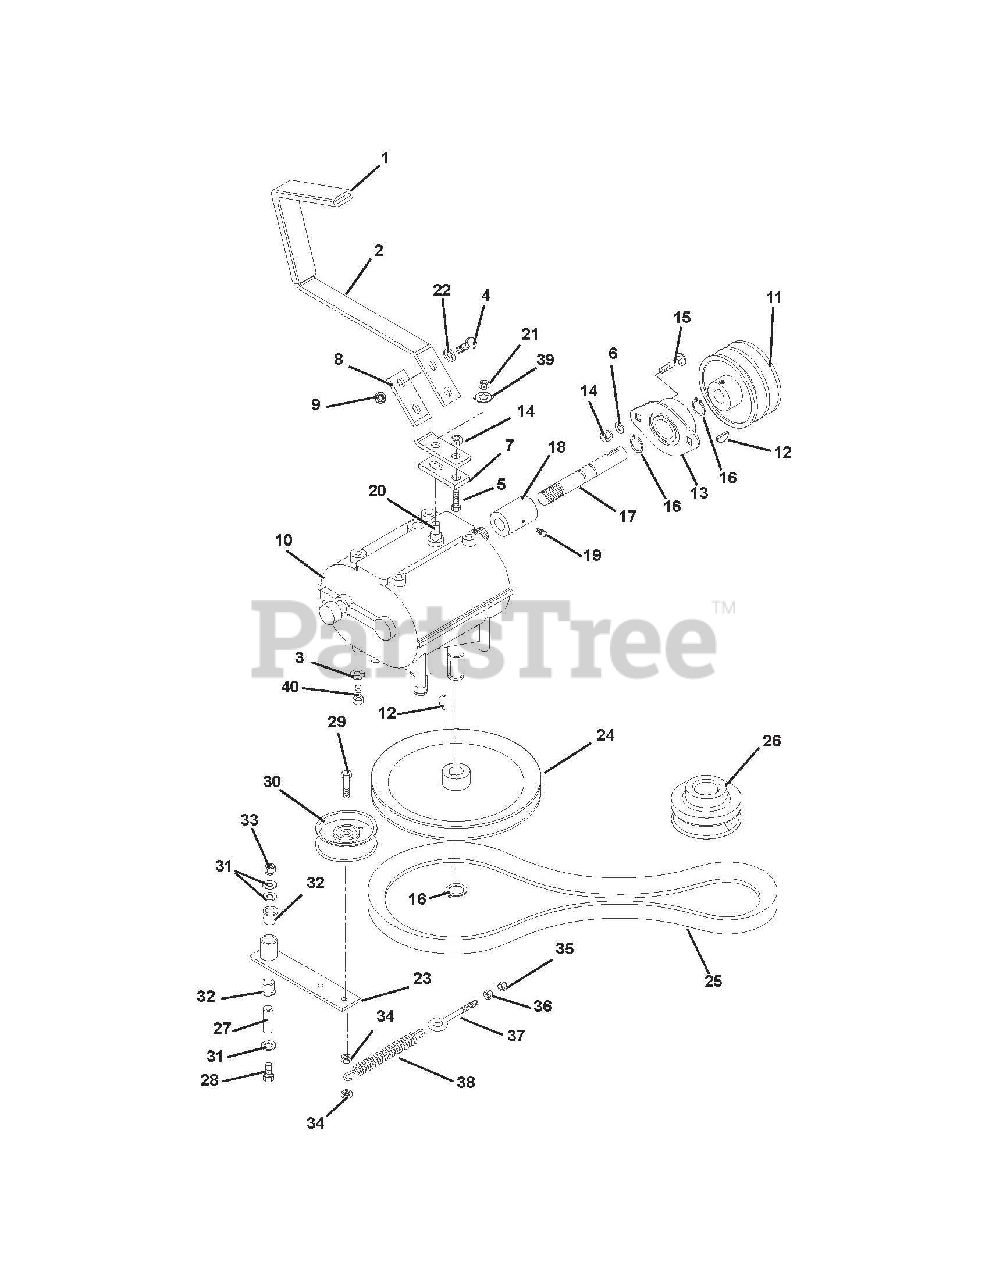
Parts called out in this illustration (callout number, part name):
2	Lever, Shifter
3	Washer-Locking .31 x .078 Regular
4	Bolt-Hex .31-18 x 1.00 Grade 5
5	Bolt-Hex .25-20 x 1.00 Grade 5
6	Washer-Flat-Steel .25 x .562 x .049
7	Plate, Shift
8	Arm, Shift
9	Nut-Locking-Top-Flange .31-18
10	Transmission
11	Sheave, Drive
12	Key-Woodruff .19 x .75
13	Bearing-Flange .625 x 1.875 x .797
14	Nut-Locking-Nylon .25-20
15	Bolt-Round Head Square Neck .25-20 x .75 Grade 5
16	Ring-Retaining-External .579 x .930
17	Shaft, Half
19	Fitting, Lube, .25-28
20	Switch-Neutral Start
21	Nut-Locking-Center .38-24
22	Washer-Flat-Steel .344 x .688 x .065
23	Weldment, Ground Drive Idler
24	Pulley-V 7.50 x .63 Sheave Transmission
25	V-Belt 4L-Section 34.385 x .531
27	Bushing, Steel .56 x .745 x 2.04
28	Bolt-Hex .50-13 x 3.25 Grade 5
29	Bolt-Hex .38-16 x 2.00 Grade 5
30	Idler-Pulley Flat 3.25 x .625
31	Washer-Flat-Steel .531 x 1.06 x .095
32	Bushing-Flange Nylon .762 x 1.00 x .58 x 1.48
33	Nut-Locking-Nylon .50-13
34	Nut-Locking-Jam-Center .375-16
35	Nut-Locking-Nylon .38-16
36	Nut-Hex .38-16
37	Eye Bolt
38	Spring, Extension
39	Washer, Locking .38 x .13
40	Bolt-Hex .31-18 x .75 Grade 5
